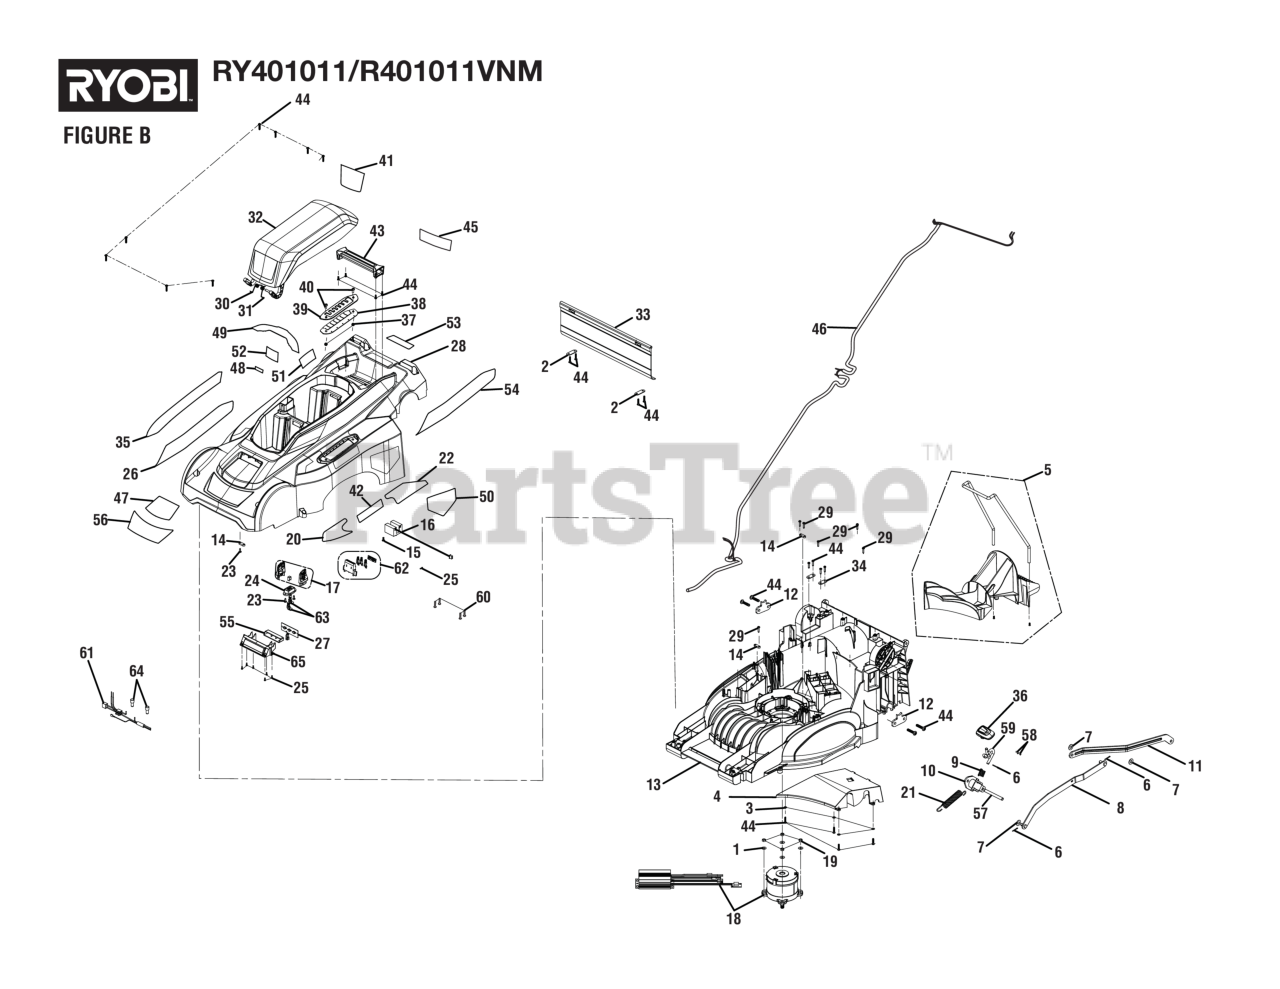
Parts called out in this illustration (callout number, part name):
1	Washer (ID6.2 x OD15 x 0.08t)
2	Axle Pressure Plate
3	Washer (ID4.5 x OD10 x 1t)
5	Mulch Plug Assembly (Inc. Key No. 6)
6	Cotter PinÏ? (2.5)
7	Washer (ID8.4 x OD18 x 1t)
8	Forward Linkage
9	Torsion Spring (Height Adjustment)
10	Height Adjustment Bracket
11	Rear Lift Rod
12	Axle Mount
13	Deck
14	Wire Press Plate
15	Screw w/Washer (M4 x 10 mm, T20 Torx Button Hd.)
16	SENSOR SWITCH FOR GRASS BAG
17	START KEY W/ HANG TAG
18	MOTOR 10035#, CONTROLLER ASSEMBLE,HUAJIE
19	Lock Nut (M6)
20	LABEL, FRONT BLACK ACCENT
21	Rentention Spring
22	LABEL, SINGLE POINT HEIGHT ADJUSTMENT
23	Screw (M4.2 x 12 mm, T20 Torx Pan Hd.)
24	Key Holder
25	Screw (M3 x 8 mm, Pan Hd., Pan Hd)
26	LABEL, RIGHT ""BRUSHLESS 20IN""
28	TOP COVER W/ LABELS
29	Screw (M4 x 16 mm, T20 Torx Pan Hd.).
30	Battery Door Right Torsion Spring
31	Battery Door Left Torsion Spring
32	Battery Cover (Inc. Key Nos. 80 & 124)
33	Rear Protective Guard
34	Pressure Plate (Height Adjustment)
35	LABEL, SIDE BLACK ACCENT
36	Height Adjustment Handle
37	Lock Nut (M5 x 0.8 mm)
38	Shifter Boot
39	Height Adjustment Plate
40	SCREW (M5 x 16 mm SOC. WASHER HD. CAP)
41	Main Warning Label (Part 2)
42	LABEL, CUT HEIGHT
43	Carry Handle
44	Screw (M4 x 20 mm, T20 Torx Pan Hd. S.T.)
45	Main Warning Label (Part 1)
46	CORD, 3PCS INNER WIRE AND PLUG ASSY
47	Ryobi 40V Lithium Label
48	Onboard Battery Storage Label
49	Start Key Warning Label
50	Danger Label (No Hands/Feet)
51	LABEL, DATA, RY401110
52	Wet Condition Battery Warning Label
53	Attachment User Callout Label
54	LABEL, LEFT ""BRUSHLESS 20IN""
55	Light Reflector
56	LABEL, FRONT ""BRUSHLESS""
57	Axle (Height Adjustment)
58	Screw (M3 x 9 mm, Flat Hd.)
59	Lever Arm
60	Screw (M4 x 10 mm, T20 Torx Pan Hd.)
62	Battery Hold Assembly
63	Female Terminal
64	Close-End Connector
65	LED Cover
